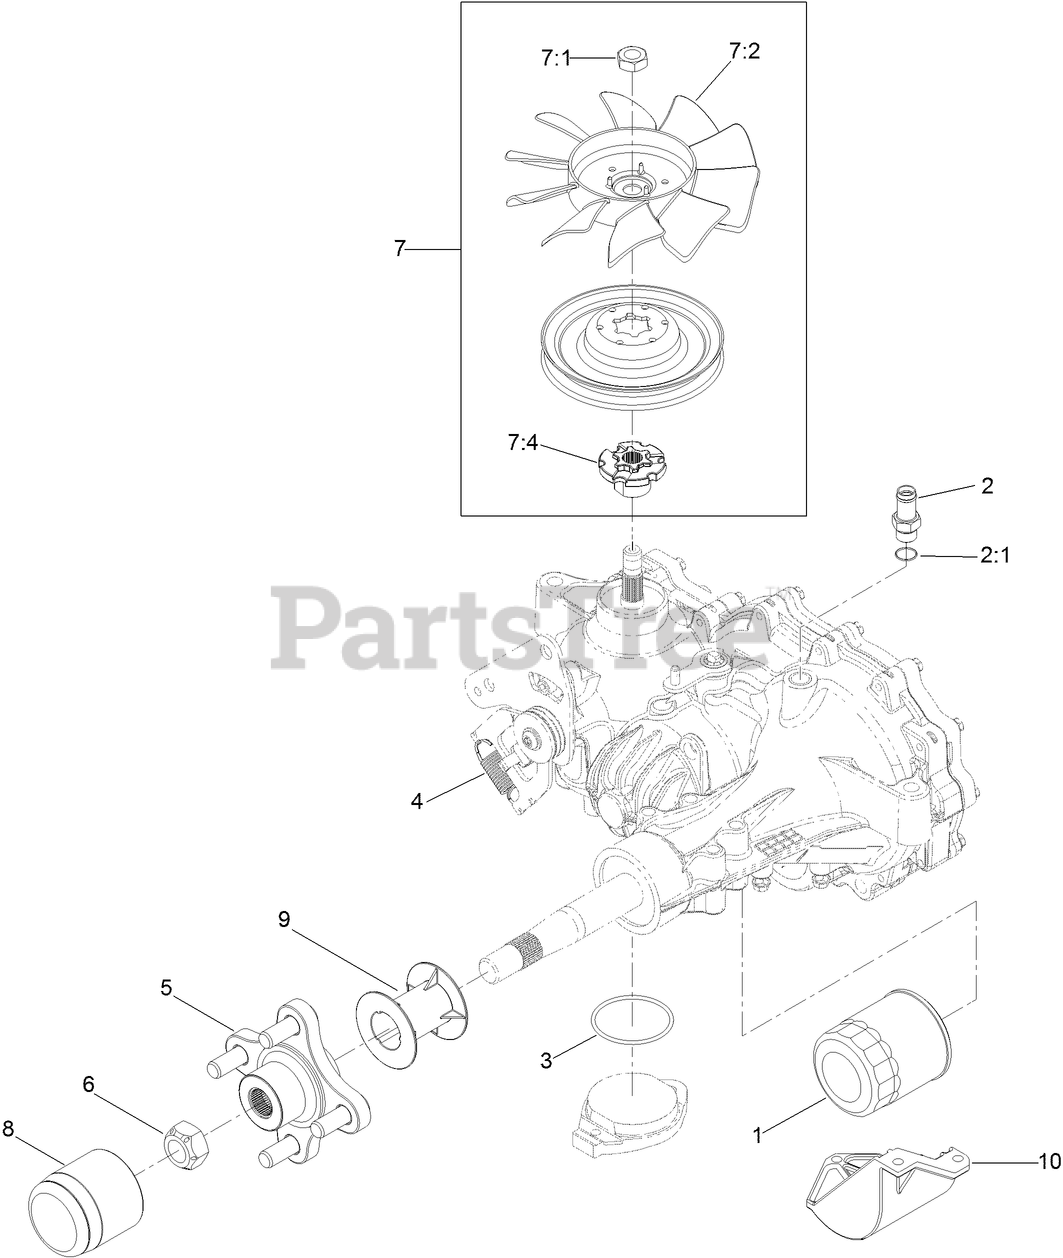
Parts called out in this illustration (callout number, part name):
1	ELEMENT-OIL FILTER, HYD
2	ADAPTER-STRAIGHT
2:1	O-RING
3	O RING-SEAL
4	SPRING-EXTENSION
5	HUB-OFFSET
6	NUT-HUB
7	FAN AND PULLEY KIT
7:1	NUT-HJ
7:4	HUB-PULLEY
8	CAP-AXLE, LONG
9	TUBE-AXLE
10	GUARD-FILTER, LH
